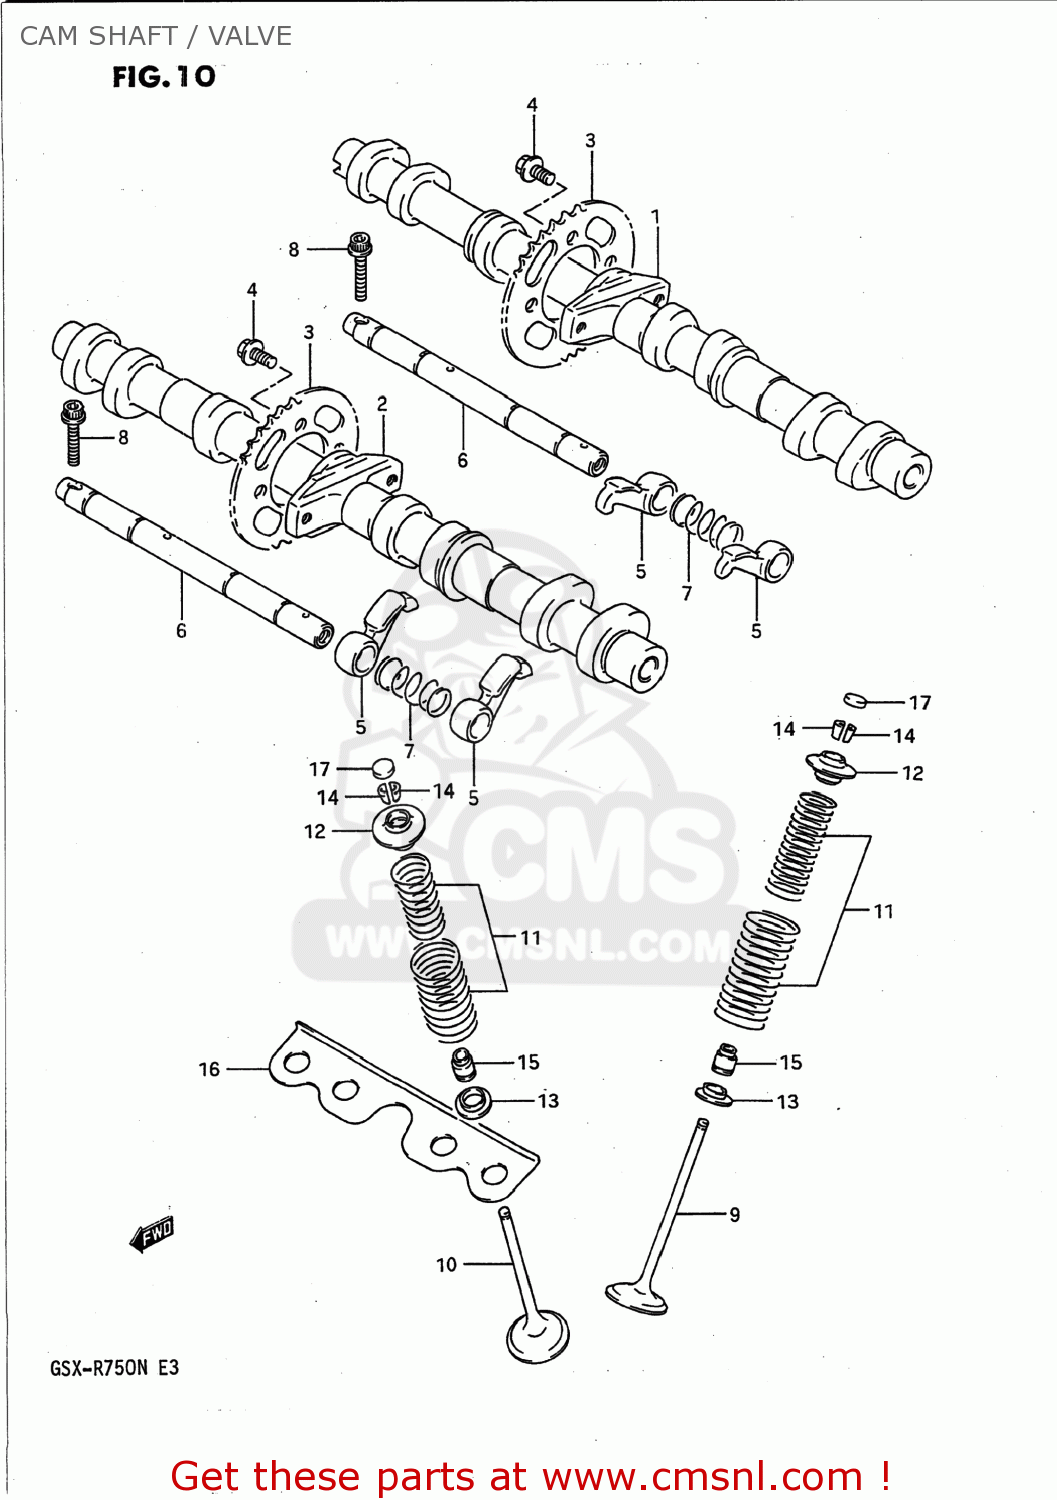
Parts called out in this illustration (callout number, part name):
1	CAMSHAFT,INTAKE
2	CAMSHAFT,EXHAUST
3	SPROCKET,CAMSHAFT
4	BOLT(7X11)
5	ARM,VALVE ROCKER
6	SHAFT,VALVE ROCKER
7	SPRING
8	BOLT
9	VALVE,INTAKE
10	VALVE,EXHAUST
11	SPRING SET,VALVE
12	RETAINER,VALVE SPRING
13	SEAT,VALVE SPRING
14	COTTER VALVE
15	SEAL,OIL(5X10X9.7)
16	PLATE
17	SHIM,TAPPET(T:2.3)
18	SHIM SET,TAPPET
19	CASE,TAPPET SHIM
